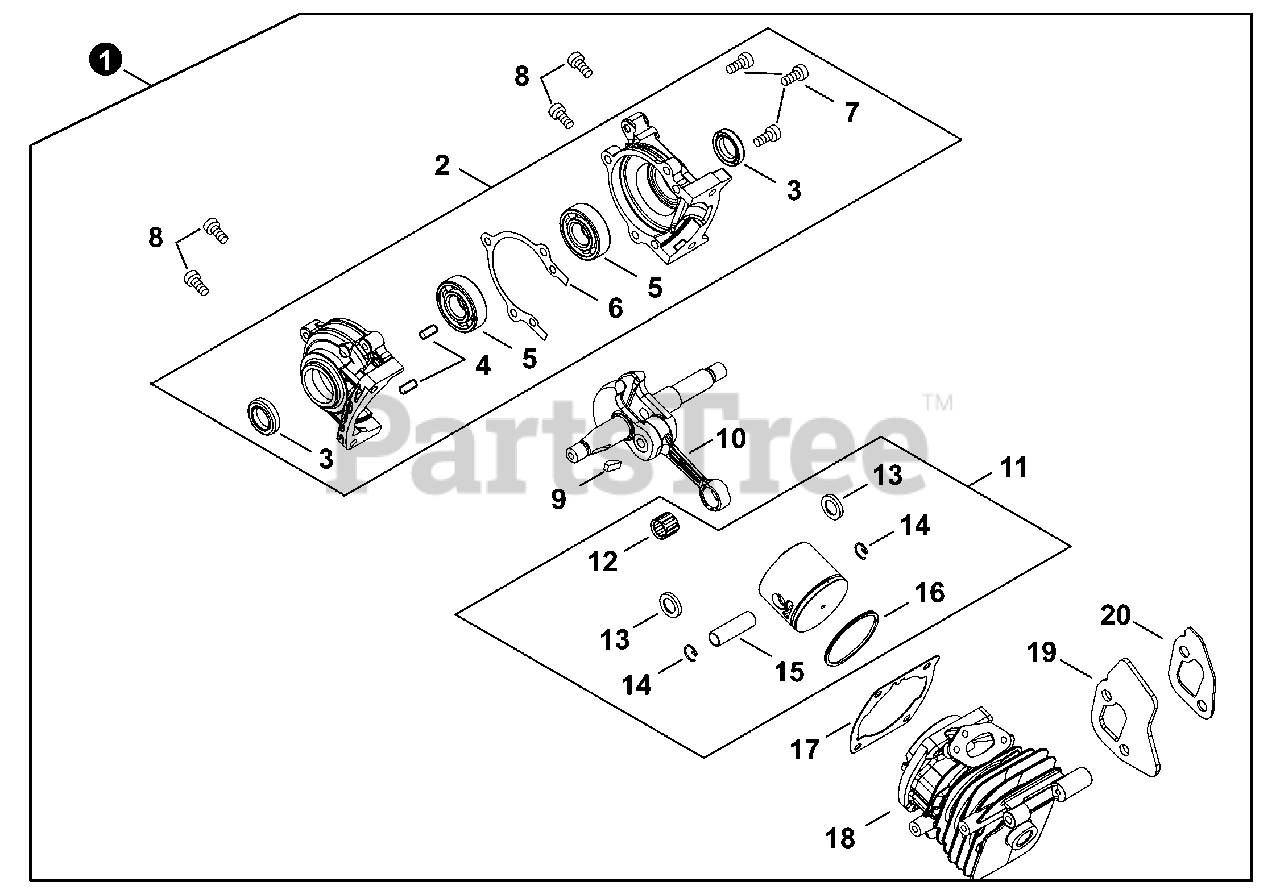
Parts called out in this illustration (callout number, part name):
1	SHORT BLOCK
2	CRANKCASE SET
3	SEAL, OIL 12
4	PIN, LOCATING 4×8
5	BEARING, BALL 6001
6	GASKET, CRANKCASE
7	BOLT, TORX 4×16
8	BOLT, TORX 4×16
9	KEY, WOODRUFF
10	CRANKSHAFT
11	PISTON KIT
12	BEARING, NEEDLE 8
13	WASHER, THRUST
14	RING, SNAP
15	PIN, PISTON 8
16	RING, PISTON
17	GASKET, CYLINDER
18	CYLINDER
19	HEAT SHIELD, EXHAUST
20	GASKET, EXHAUST
